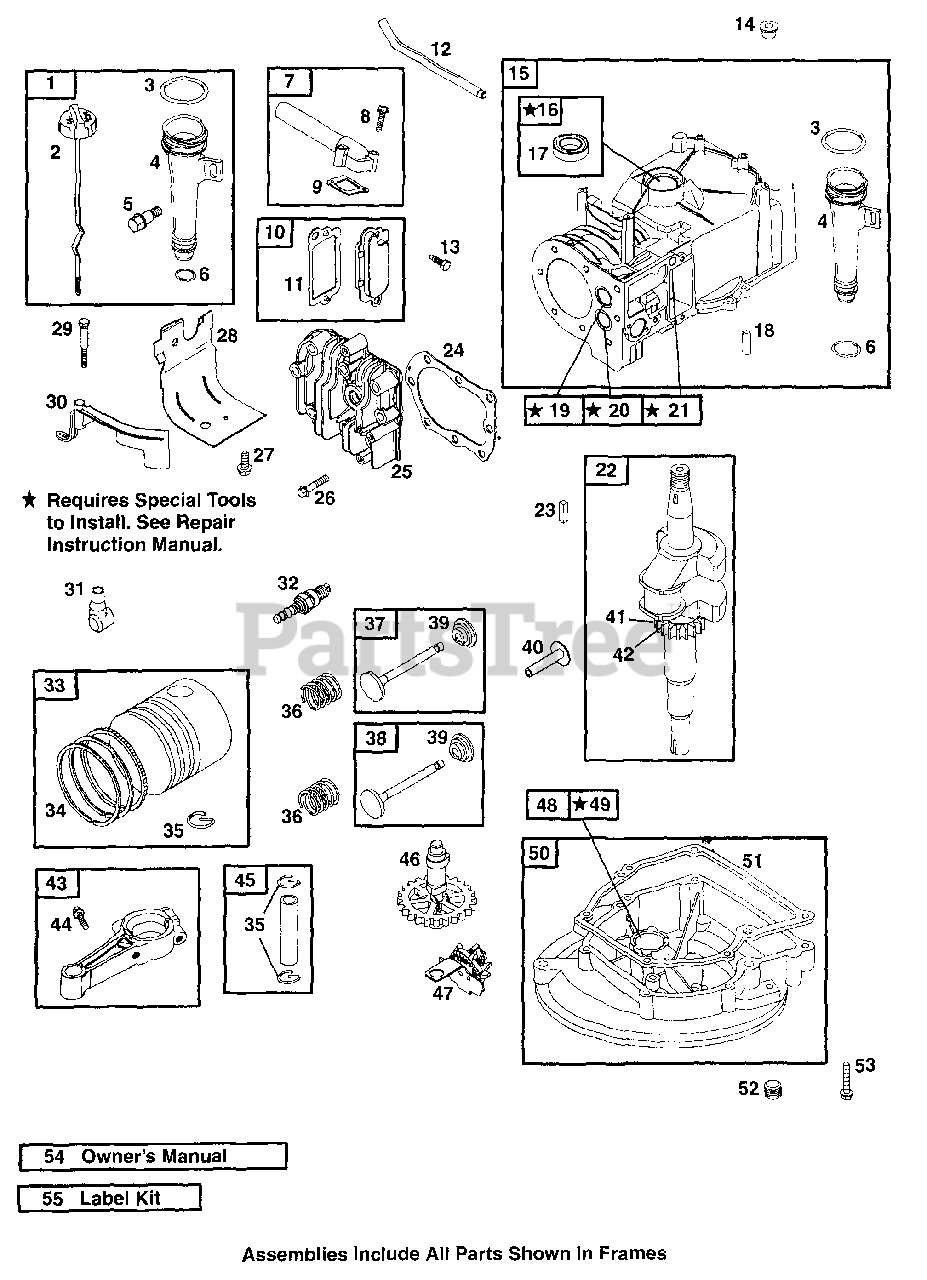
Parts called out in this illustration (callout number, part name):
1	Dipstick/Tube Assembly
3	Dipstick/Tube Seal
4	Dipstick Tube
5	Screw (Dipstick Tube)
6	Dipstick Tube Seal
7	Intake Manifold
8	Screw (Intake Manifold)
9	Intake Gasket
10	Breather Assembly
11	Breather Gasket
12	Breather Tube
13	Screw (Breather Assembly)
15	Cylinder Assembly
16	Bushing/Seal Kit
17	Oil Seal (Magneto Side)
18	Locating Pin
19	Valve Seat (Intake)
20	Valve Seat (Exhaust)
21	Guide Bushing (Exhaust Valve)
22	Crankshaft
23	Flywheel Key
24	Cylinder Head Gasket
25	Cylinder Head
26	Screw (Cylinder Head)
27	Screw (Cylinder Shield)
28	Cylinder Shield
29	Screw (Governor Blade)
30	Governor Blade
31	Spark Plug Boot
32	Spark Plug
33	Piston Assembly (Standard)
34	Ring Set (Standard)
35	Piston Pin Lock
36	Valve Spring
37	Exhaust Valve
38	Intake Valve
39	Valve Retainer
40	Valve Tappet
41	Locating Pin
42	Timing Gear
43	Connecting Rod
44	Screw (Connecting Rod)
45	Piston Pin (Standard)
47	Governor/Oil Slinger
48	Oil Seal (PTO Side)
49	Bushing/Seal Kit (PTO Side)
50	Engine Sump
51	Crankcase Gasket (.015 Thick, Std)
52	Oil Drain Plug
53	Screw (Crankcase Cover)
54	Owner's Manual
